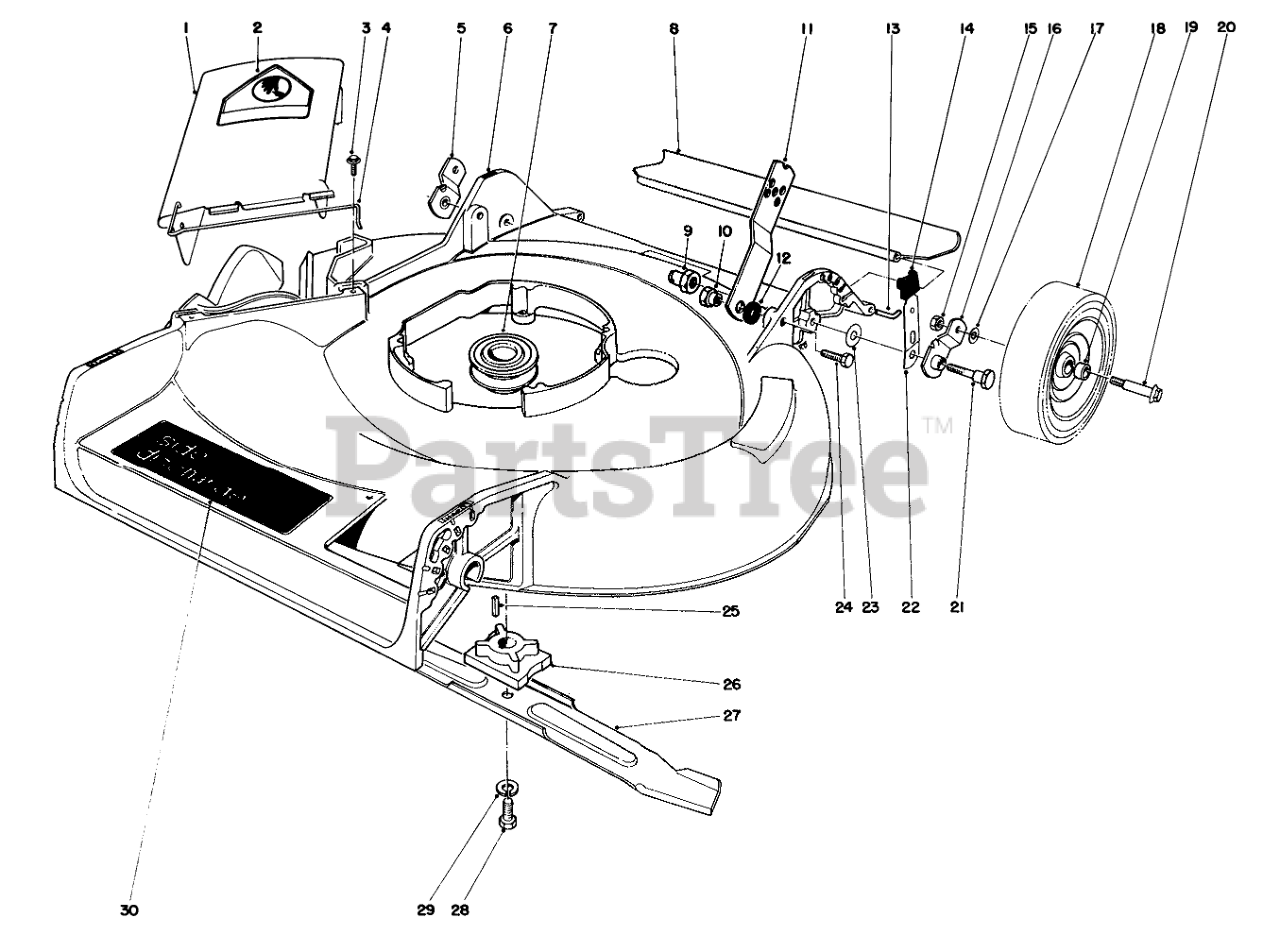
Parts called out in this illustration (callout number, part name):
1	Deflector (Incl. Ref #2 & 4)
2	DECAL-DANGER
3	SCREW AND WASHER ASM
4	SPRING HINGE
5	Pivot Arm
6	Housing
7	Pulley
8	Rear Shield
9	HANDLE PIVOT NUT
10	HANDLE PIVOT NUT
11	Handle Latch
12	SPACER
13	SHIELD ROD
14	KNOB-ARM
15	Nut
16	Pivot Arm
17	WASHER
18	Wheel & Tire Assembly (Incl. Ref. #19)
19	BUSHING
20	BOLT-WHEEL
21	5/16-18 PIVOT SCREW
22	SPRING ARM ASM
23	WASHER-PIVOT
24	SCREW-HH
25	Key Square
26	Blade Retainer
27	Blade
28	SCREW-HH
29	WASHER-LOCK
30	Decal-Side Discharge
